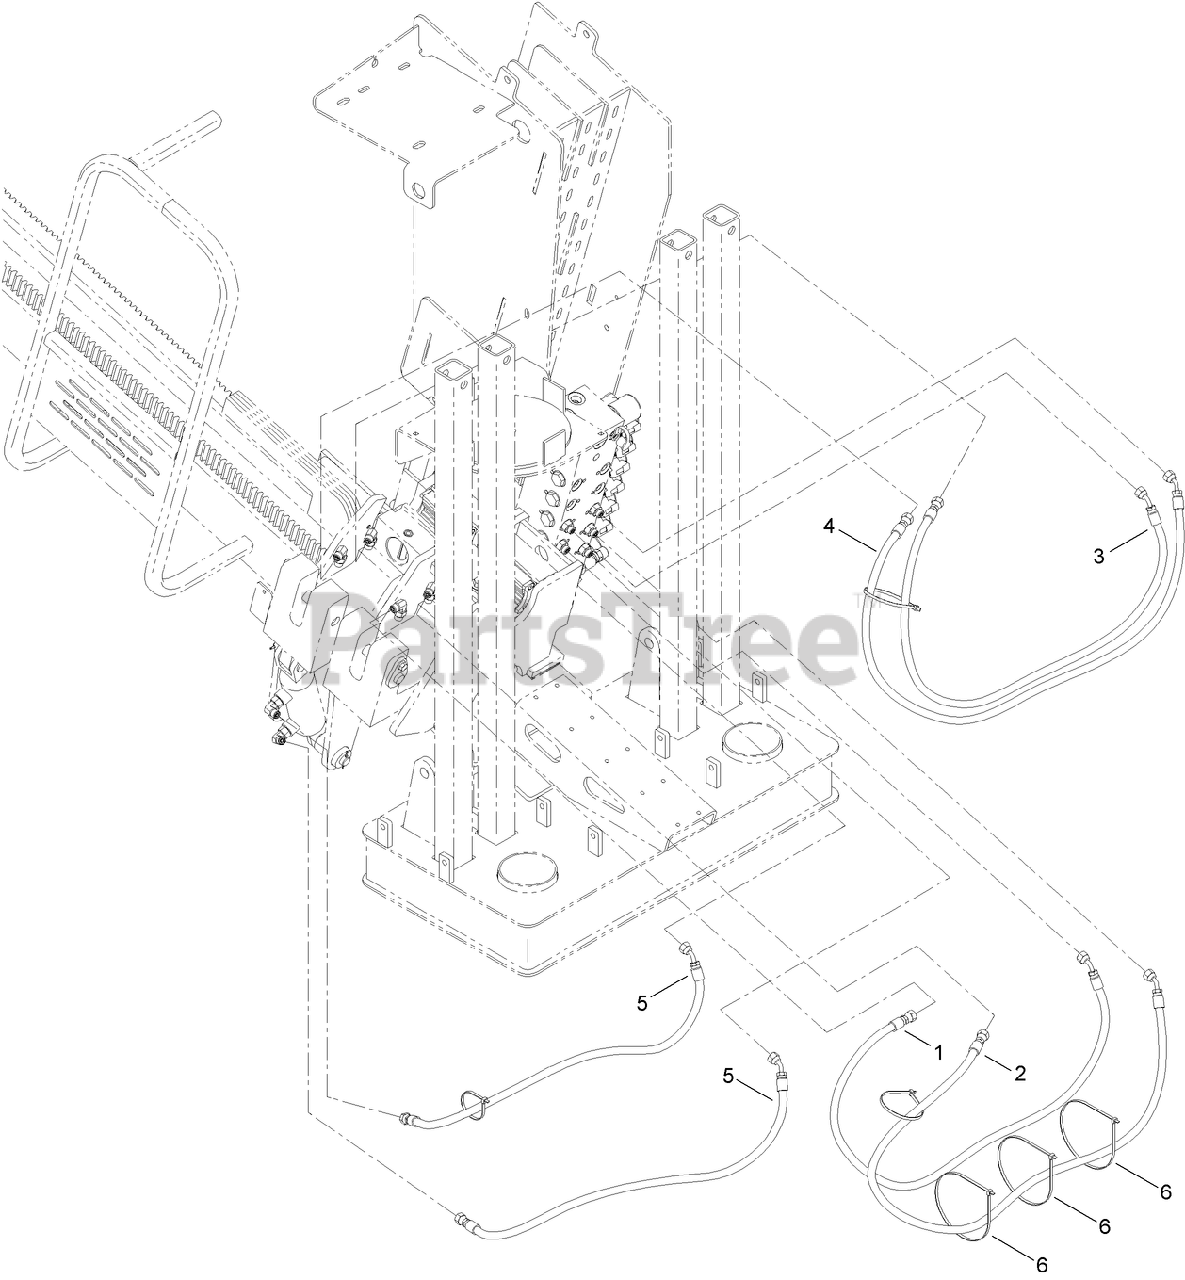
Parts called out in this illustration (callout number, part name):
1	HOSE ASM
2	HOSE ASM
3	HOSE ASM
4	HOSE ASM
5	HOSE ASM
6	TIE-CABLE
